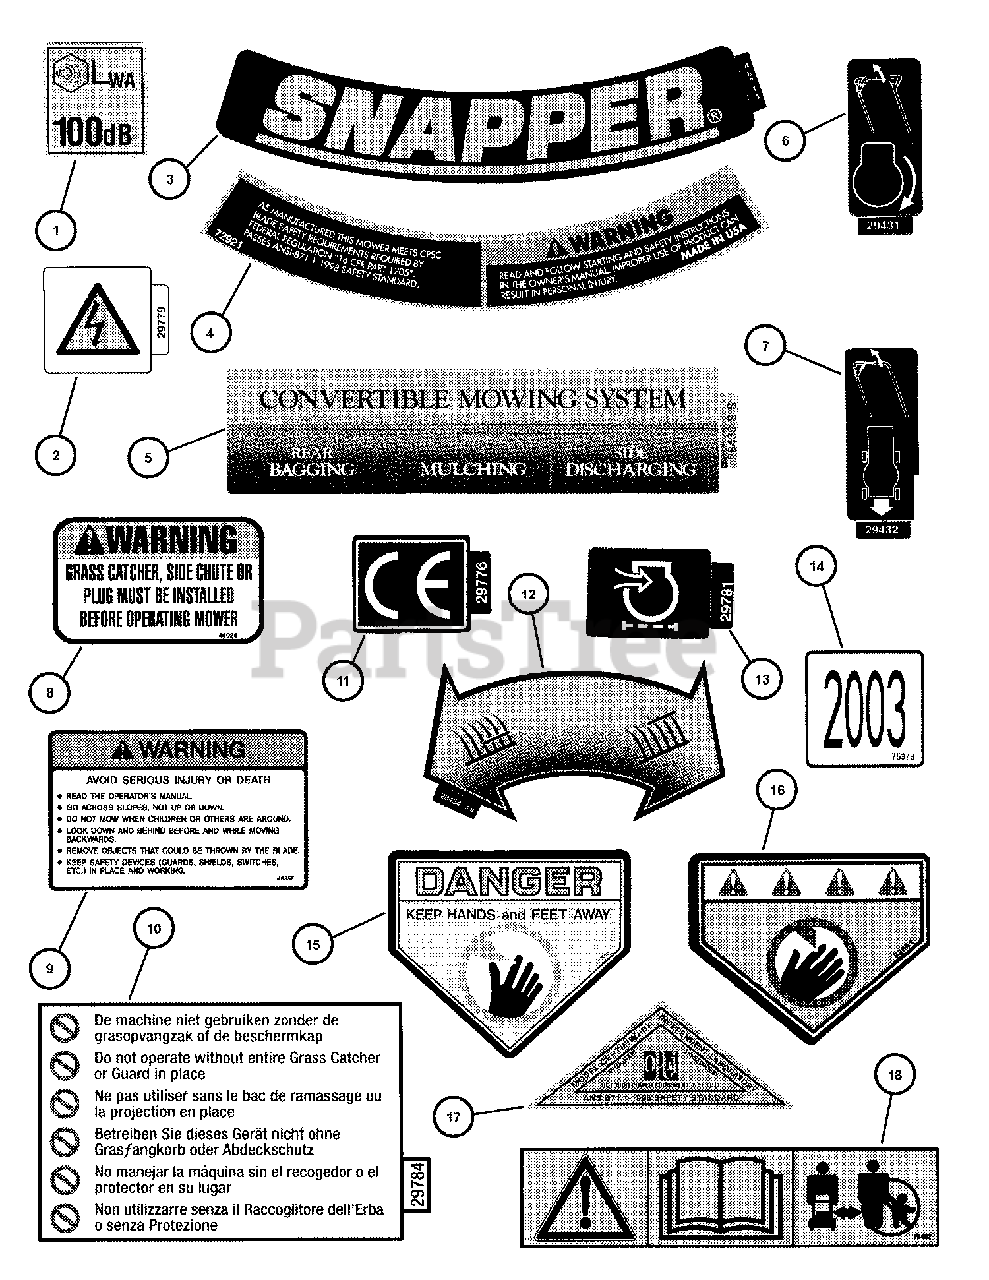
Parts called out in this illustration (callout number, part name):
1	DECAL, Sound 100 dB (Euro)
2	DECAL, Spark Plug International Symbol
3	DECAL, "SNAPPER" (5HP & 6HP)
3	DECAL, "SNAPPER" Black/Gold (6-3/4HP)
3	DECAL, "SNAPPER" (ELP21702BV)
4	DECAL, Warning (Deck)
5	DECAL, Convertible Mower
6	DECAL, (OPC) Operator Presence Control
7	DECAL, Ground Drive, (Cast Al Comm)
8	DECAL, Chute Deflector Warning
9	DECAL, Warning 1997
10	DECAL,Deck/Chute International Warning
11	DECAL, Euro Community (CE)
12	DECAL, Height Adjustment (Euro)
13	DECAL, Air Filter International Symbol
14	DECAL, 2003 Year of Mfg.
15	DECAL, Danger, Cut Finger
16	DECAL, Warning (Deck) (Euro)
17	DECAL OPEI Ride-On
18	DECAL, Caution Symbols
